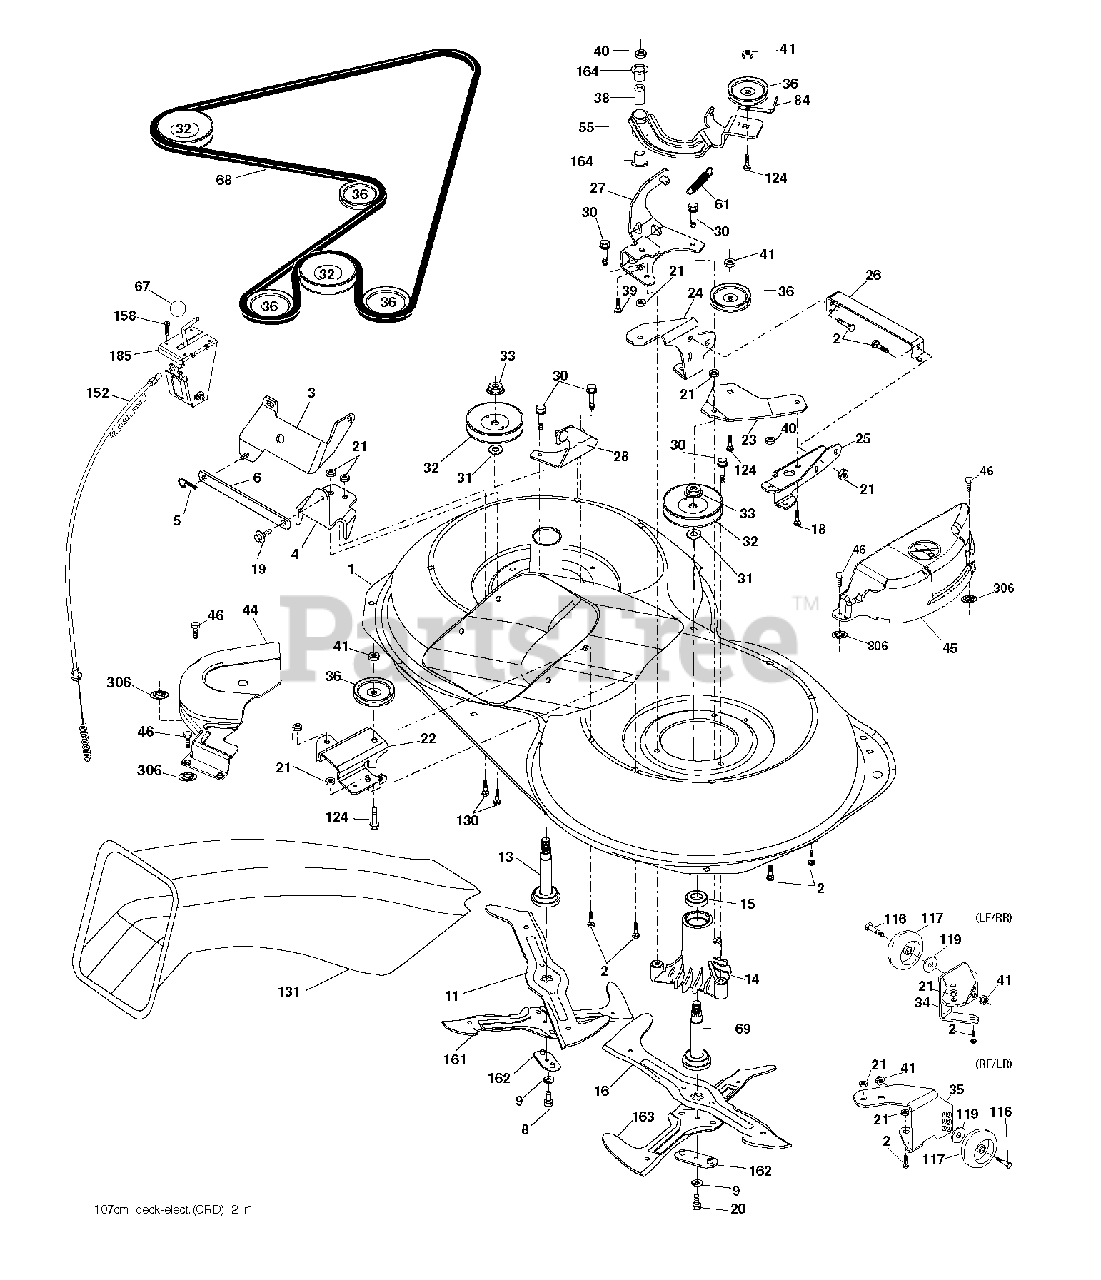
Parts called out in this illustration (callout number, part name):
2	BOLT
3	BRACKET.ASM.BAR.SWAY.CHASS
5	RETAINER-SPRNG RB
6	BAR SWAY
8	Bolt, 3/8-24 X 1.25 Gr8
9	LOCKWASHER
11	BLADE.3N1.LH.CRD
13	SHAFT ASM VENT
16	BLADE.3N1.RH.CRD
19	BOLT SHD 5/16-18
20	BOLT.3/8-24X1.25GR8. LHTHRD
21	LOCKNUT
22	BRACKET
23	BRACKET
27	BRACKET
30	SCREW, WASHER HEAD
31	WASHER.SPACER.MANDREL
33	NUT.FLANGE.LOCK.TOP
36	PULLEY.IDLER.4.25
40	LOCKNUT
41	NUT LOCK FLG 3/8-16 UNC
46	SCREW.1/4-20X5/8
67	KNOB T (3/8 HOLE)
68	HEX-BELT 107 MOWER
69	SHAFT.ASM.W/LWR.BRG.RH.THREAD
84	KEEPER, BELT IDLER
116	BOLT.SHOULDER.3/8-16X3-5/8
117	WHEEL. GUAGE RALLY
124	BOLT.3/8-16X1.50
158	SCREW
164	BRNG T
185	HEAD ASM. CABLE CLUTCH
